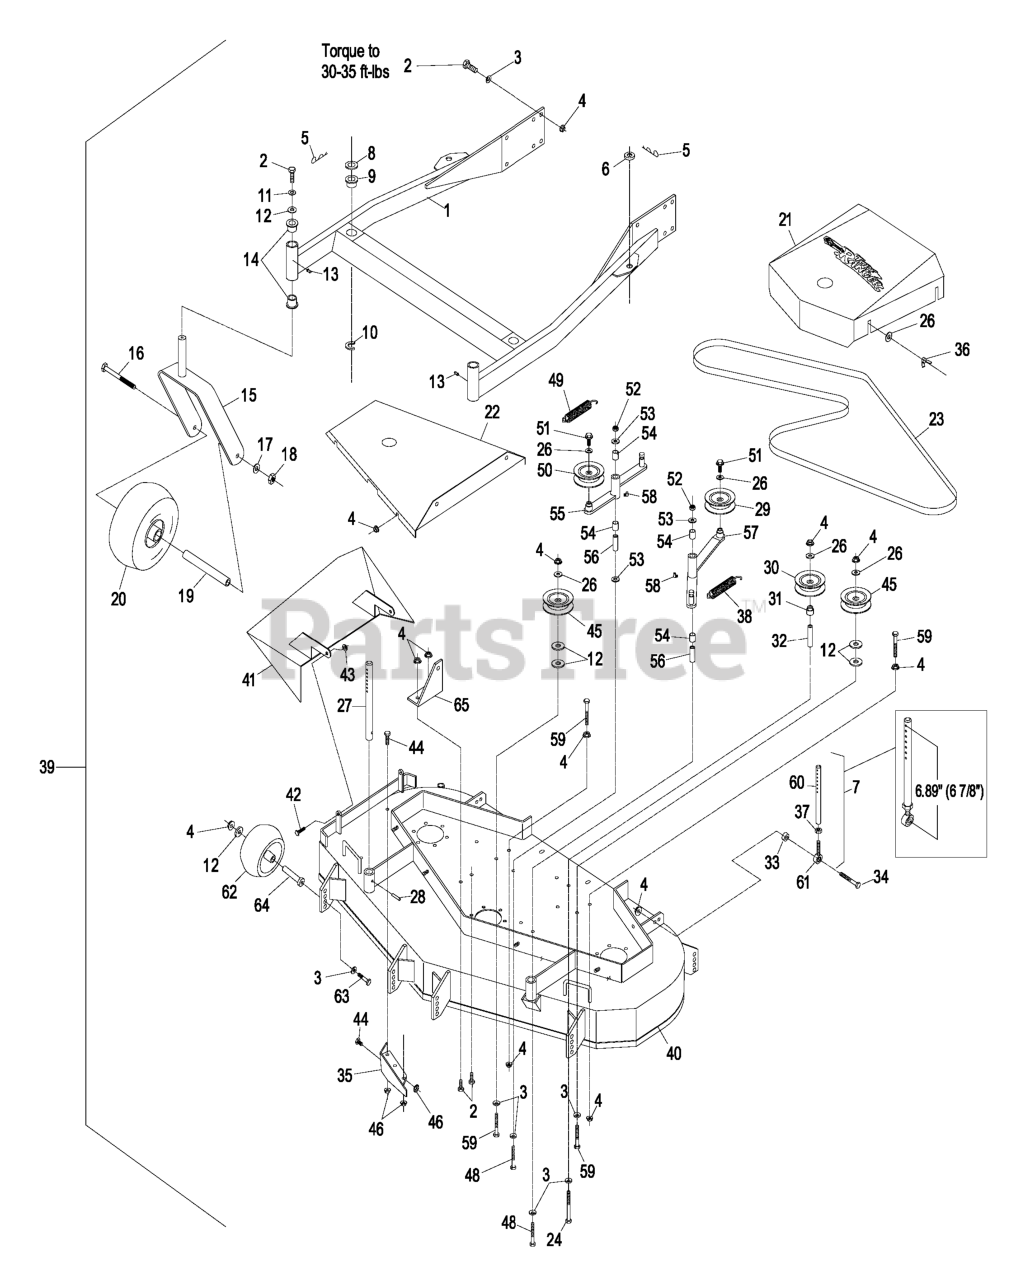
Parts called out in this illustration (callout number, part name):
3	WASHER-BELLEVILLE
4	NUT-HHF, WHIZ
5	PIN,HAIR COTTER
8	SPACER-DECK SUPPORT
9	BUSHING-DECK
10	RING-RETAINING
11	WASHER-LOCK
13	FITTING-GREASE
14	BEARING-FLANGED
16	SCREW-HH
17	WASHER-LOCK
18	NUT-HH
19	SPACER
21	COVER W/DECAL TR/FMD523
23	BELT,BLADE DRIVE
24	SCREW-HH
25	Asm,Complete Deck
26	WASHER-FLAT
27	ROD,DECK SUPPORT
29	PULLEY-IDLER
30	PULLEY-IDLER
31	BUSHING,IDLER
32	SPACER-ANCHOR, CLUTCH
34	SCREW-HH
35	WLD,BAFFLE DISCHARGE
36	NUT-WING
37	NUT-HEX
38	SPRING-EXTENSION
39	Asm,Complete Deck
41	WLD,CHUTE DISCHARGE
42	SCREW-HH
43	NUT-LOCK, NI
44	SCREW-HH
45	IDLER,PULLEY
47	KIT, SP CASTER WHEEL REPL
48	SCREW-HH
49	SPRING-EXTENSION
50	IDLER,PULLEY
51	Screw, Whizlock 3/8-16 X 1
52	NUT-LOCK, NI
53	WASHER-FLAT
54	SLEEVE-BEARING
55	ASM,IDLER ARM
56	BUSHING-PIVOT, IDLER
57	ASM,IDLER ARM
58	FITTING-GREASE, 90 DEG
59	SCREW-HH
60	LINK,SUPPORT
61	BALLJOINT
62	ROLLER-SCALP, ANTI
63	SCREW-HH
64	BUSHING-ROLLER
65	BRACKET,SPRING ANCHOR
